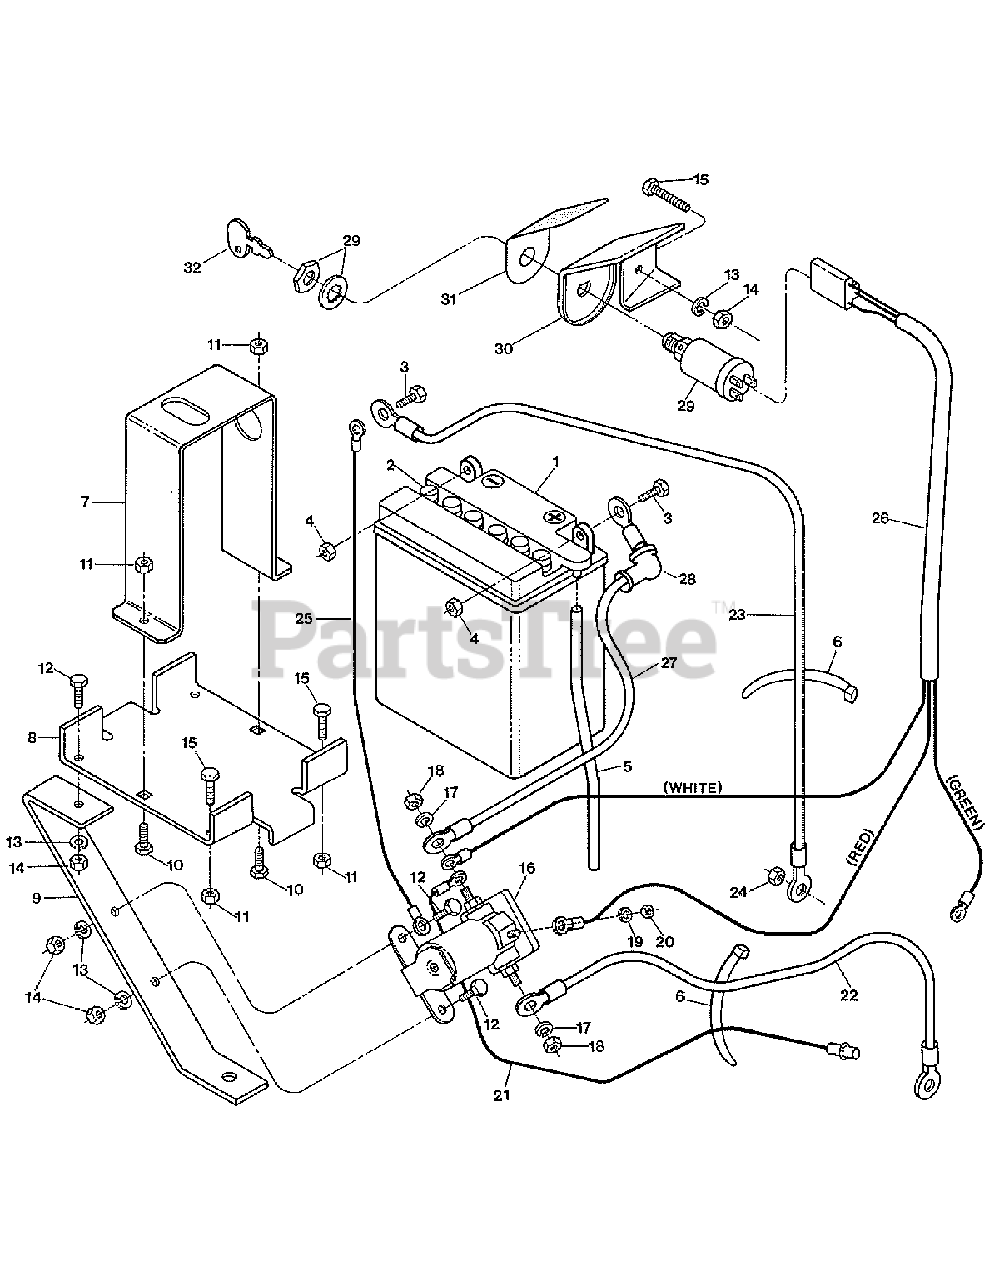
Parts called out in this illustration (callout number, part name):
1	BATTERY (INCL. 2-5)
2	CAP-YELLOW
3	HDW PKG-BATTERY TERMINAL (INCL. 2 NUTS REF. NO. 4)
4	HDW PKG-BATTERY TERMINAL (INCL. 2 SCREWS REF. NO. 3)
5	TUBE-VENT BATTERY/HSE
6	TIE-RED
7	CLAMP-BATTERY PNT
8	BRKT-BATT BASE PNT
9	SUPT-BATT BRKT PNT
10	SCR-HHCS 1/4-20X1 GR5
11	NUT-H/LK 1/4-20
12	SCR-HHCS 1/4-20X5/8 GR5
13	WASHER-LK .25 ZP
14	NUT-HEX 1/4-20 ZP
15	SCR-HHCS 1/4-20X1.250 GR 5
16	KIT-SOL W/HDW (INCL. 17-20)
17	WASHER-LK .312 ZP
18	NUT-HEX 5/16-24
19	WASHER-EXTERNAL TOOTH 1
20	NUT-HH M10-32X.125
21	ASSM-WIRE
22	CABLE-STRT TO SOLND
23	CABLE (-)
24	NUT-HEX 5/16-18 ZP
25	ASSM-GROUND WIRE
26	WIRE HARNESS TO KEYSWITCH
27	CABLE-BTRY TO SOLND (USE WITH NO. 28)
28	BOOT-BATTERY CABLE
29	KEYSWITCH W/KEYS (INCL. 32 AND MOUNTING WASHER & NUT)
30	BRKT-KEYSWITCH W/DECAL (INCL. 31)
31	DECAL-IGNITION
32	KEYS(1 PAIR) FOR SWITCH
